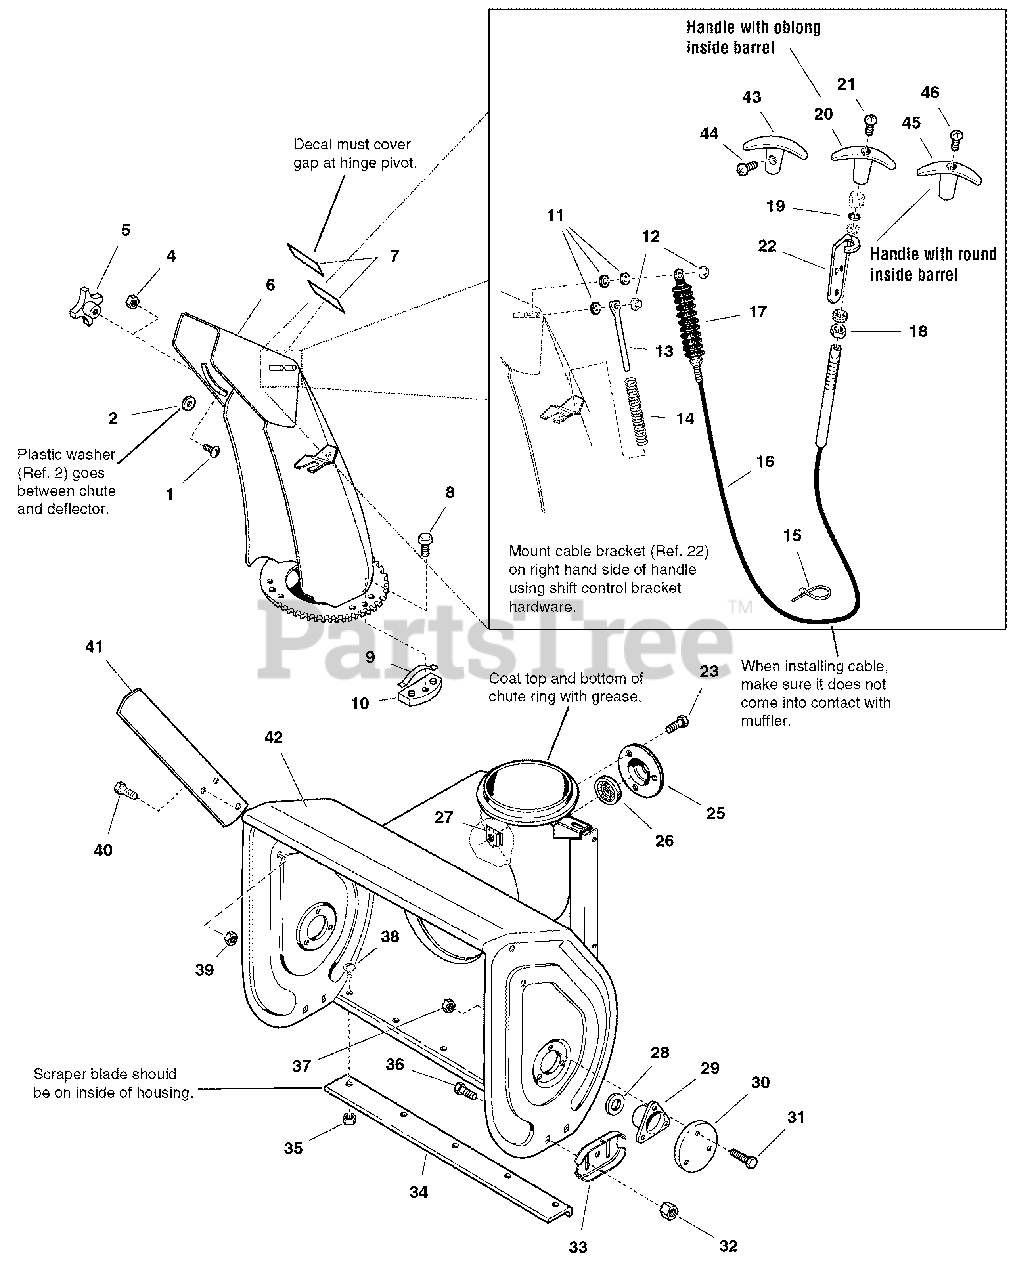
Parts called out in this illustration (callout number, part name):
1	CARRIAGE BOLT, 5/16-18 x 3/4 G5
2	WASHER, Nylon
4	NUT, Hex Flange ESNA Light, 5/16-18 (Used on all models Except 24 in. Models)
5	KNOB, Internal Thread, 5/16 (Used Only on 24 in. Models)
6	CHUTE AND DEFLECTOR ASSEMBLY, Manual
6	CHUTE AND DEFLECTOR ASSEMBLY, w/Remote
7	DECAL, Orange Strip
8	SCREW, Hex Washer Head Pastite, 10-14 x 5/8
9	SPRING, Flat
10	HOLD DOWN, Chute
11	SPACER, 17/64 ID x 3/8 OD
12	NUT, Push 1/4
13	ROD, Spring
14	SPRING, Compression
15	TIE, Self Locking (Used on all models Except 24 in. Models)
16	CABLE AND KNOB ASSEMBLY, Chute (Includes Ref. No. 17, 18, 19, 20 & 21)
17	BOOT, Bellows
18	COLLET
19	SEAL, Rod
20	KNOB
21	SCREW, 8-32
22	BRACKET, Cable
23	CAPSCREW, Hex Head, 5/16-18 x 5/8 G5
25	RETAINER, Bearing
26	BEARING, Ball
27	NUT, Retainer Speed, 5/16-18
28	SPACER, Low
29	BEARING, Flange
30	CAP, Bearing, 3-3/4OD
31	CAPSCREW, Hex Head 5/16-18 x 7/8 G5
32	NUT, Hex Flange 3/8-16 ESNA
33	SKID SHOE, Reversible
34	BLADE, Scraper, 24 in.
34	BLADE, Scraper, 28 in.
34	BLADE, Scraper, 32 in.
35	NUT, Hex Flange, 5/16-18, Two-Way Lock GA (Quantity 7 Only on 32 in. Models)
36	CARRIAGE BOLT, 3/8-16 x 3/4
37	NUT, Hex Flange, 5/16-18
38	CARRIAGE BOLT, 5/16-18 x 5/8 G5 (Quantity 7 Only on 32 in. Models)
39	NUT, Hex Keps, 5/16-18, Conical Washer (Used on all models Except 24 in. Models)
40	CAPSCREW, Hex Head, 5/16-18 x 3/4 G5 (Used on all models Except 24 in. Models)
41	CUTTER, Drift, 1/4 in. Thick, 20LG (Used on all models Except 24 in. Models)
42	HOUSING AND IMPELLER ASSEMBLY, 24 in.
42	HOUSING AND IMPELLER ASSEMBLY, 28 in.
42	HOUSING AND IMPELLER ASSEMBLY, 32 in.
44	SCREW, Set, Hex #10-24 x 3/8
45	HANDLE "T"
46	SCREW, Round Head
